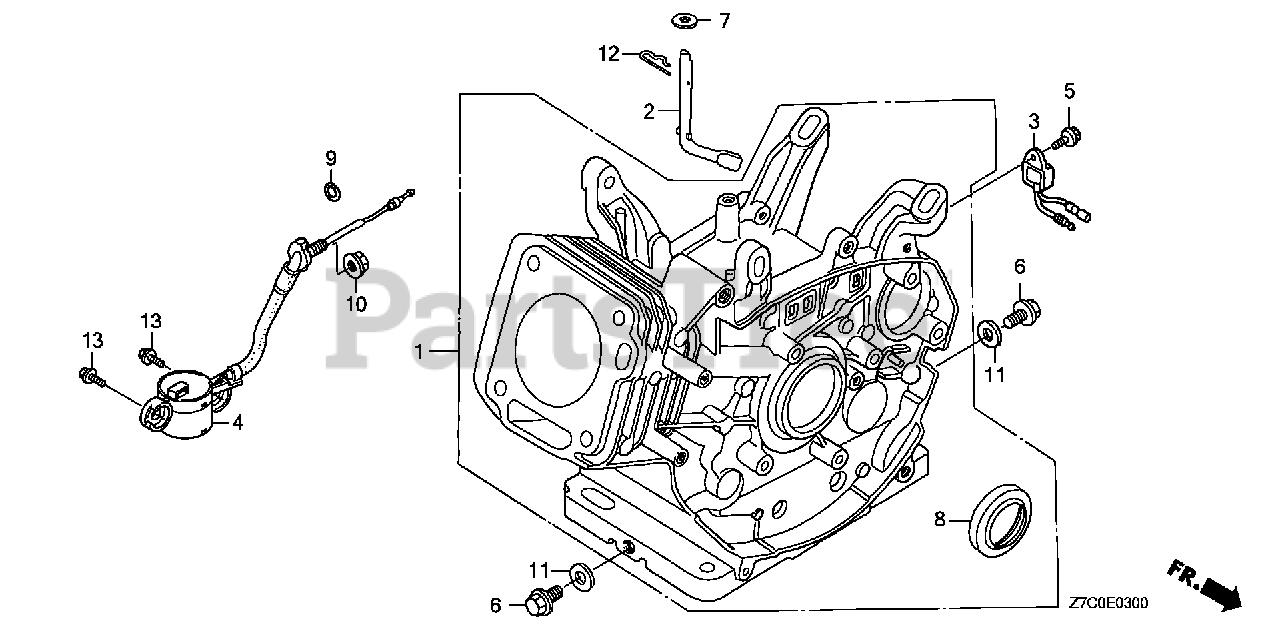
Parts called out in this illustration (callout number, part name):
1	CYLINDER ASSY. (ALERT)
2	SHAFT, GOVERNOR ARM
3	ALERT UNIT, OIL
4	SWITCH ASSY., OIL LEVEL
5	BOLT, FLANGE (6X12) (CT200)
6	BOLT, DRAIN PLUG (12X15)
7	WASHER (8.2X17X0.8)
8	OIL SEAL (30X46X8)
9	O-RING (14MM)
10	NUT, FLANGE (10MM)
11	WASHER, DRAIN PLUG (12MM)
12	PIN, LOCK (10MM)
13	BOLT, FLANGE (6X12)
